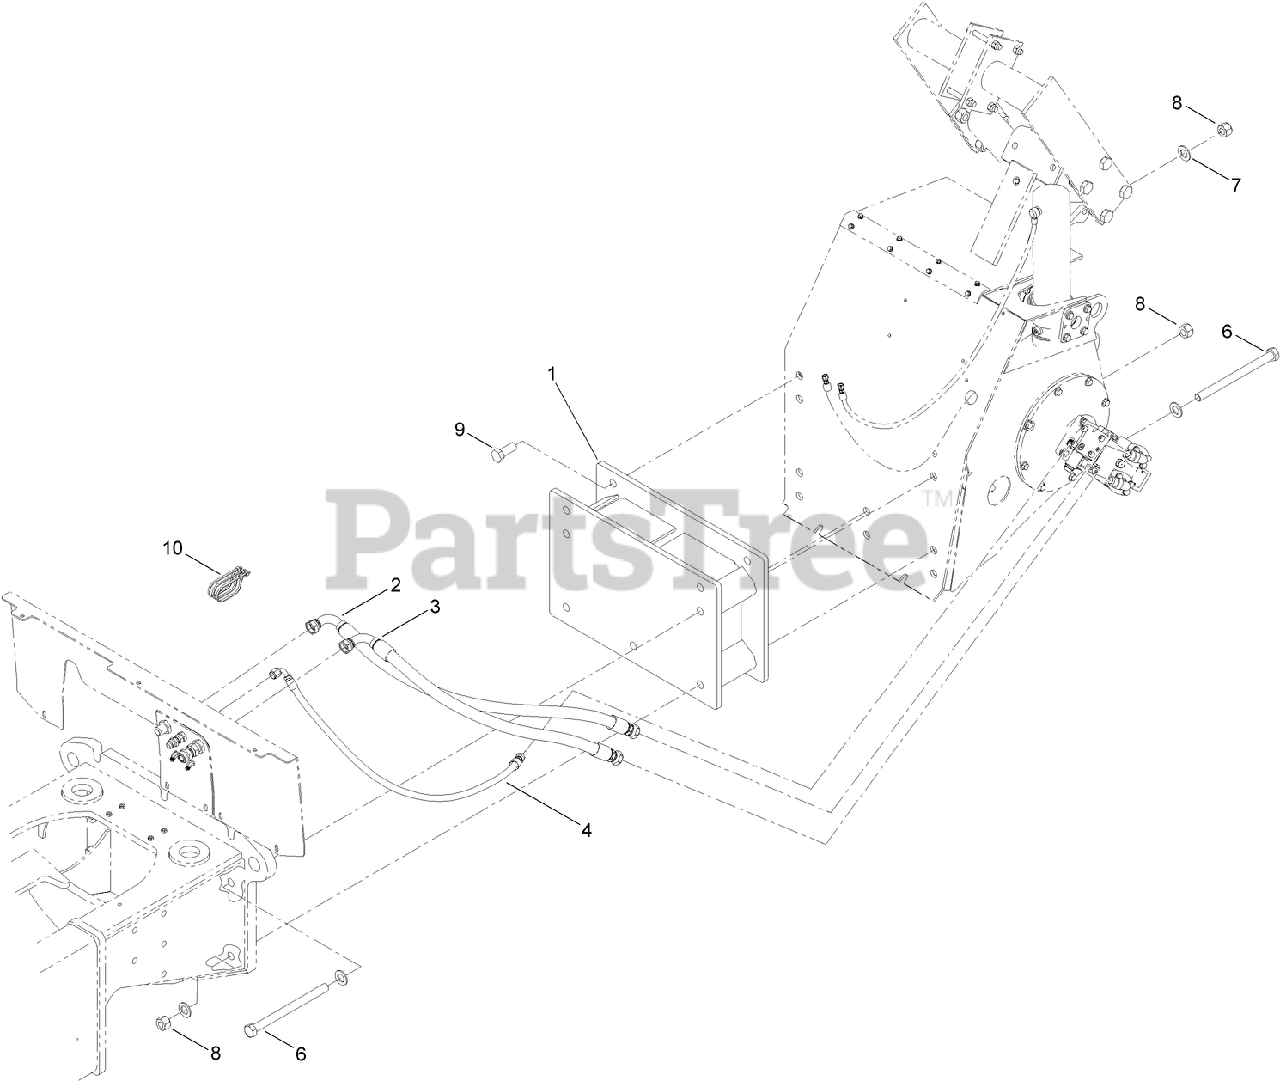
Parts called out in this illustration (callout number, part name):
1	ADAPTER-FRAME
2	HOSE ASM
3	HOSE ASM
4	LP HYD HOSE ASM
6	SCREW-HH
10	STRAP-TIE
